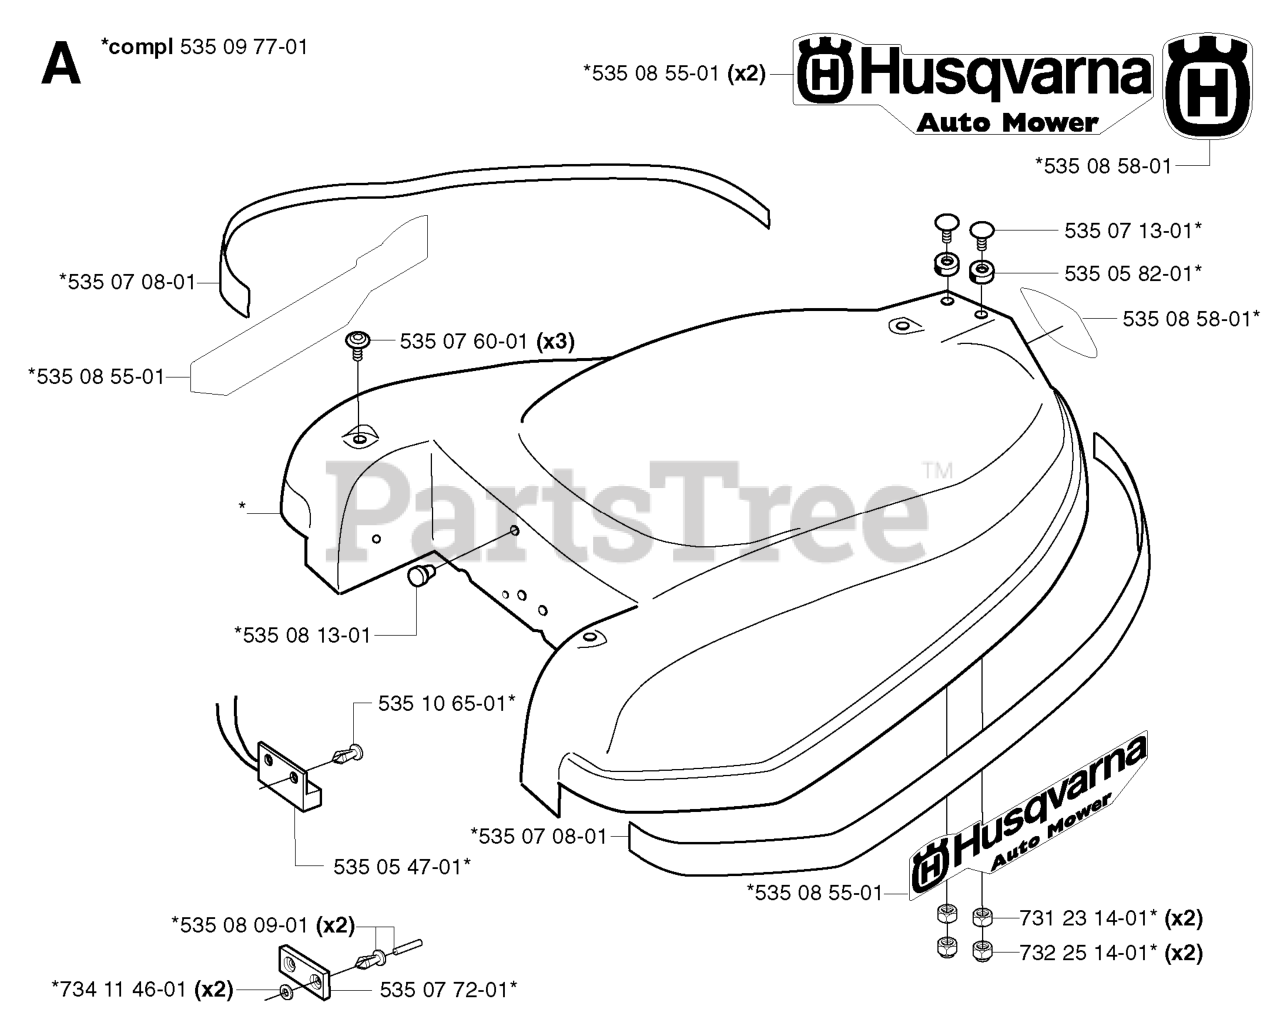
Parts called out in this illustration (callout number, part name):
1	SEAT, GRAY
2	SEAT PIVOT BRKT
3	STRAP
4	BOLT,SHOULD
7	SPRING COMPRESSION
8	BOLT.5/16-18UNCX3/4 W/SEMS.BLK
10	PAN, SEAT
12	BRKT SWITCH
14	BOLT.ROUND.HEAD.SQUARE.NECK
15	SPACER SPLIT
16	SPRING COMPRESSED
17	NUT T
19	KNOB.SEAT.ADJ.WINGNUT
20	CAP SPRING
21	BOLT.SHOULDER.5/16-18
22	NUT.71038.31-18.HEX.NYLOCK
